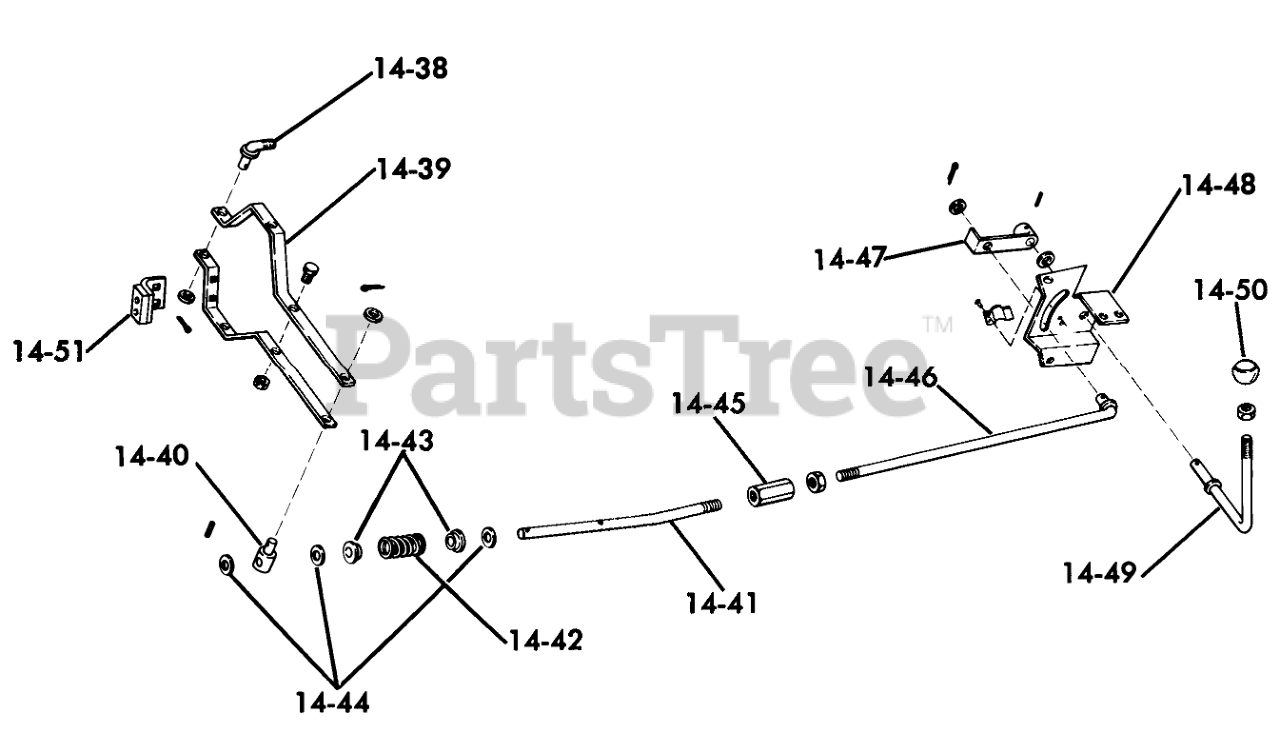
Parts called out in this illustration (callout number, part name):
14-20	RING EXTERNAL
14-21	ASSY COLLAR
14-22	BEARING
14-23	RING INTERNAL
14-24	ASSY CLUTCH PLATE
14-27	RING EXTERNAL
14-28	PULLEY CLUTCH
14-29	BEARING
14-30	RING INTERNAL
14-31	WASHER
14-32	SPRING WASHER
14-33	Assy-Outer Clutch
14-35	WASHER
14-36	INTERNAL RING
14-37	END CAP
14-38	ASSY HOOK
14-39	ASSY-CLUTCH BAR R
14-40	TRUNION
14-41	CLUTCH ROD
14-42	SPRING
14-43	Bushing
14-44	Washer
14-45	TURN BUCKLE NUT
14-46	Assy-Clutch Rod
14-47	ARM CLUTCH ENGAGE
14-48	BRACKET
14-49	ASSY CLUTCH HANDLE
14-51	Clutch Brake
14-53	Bracket-Brake
